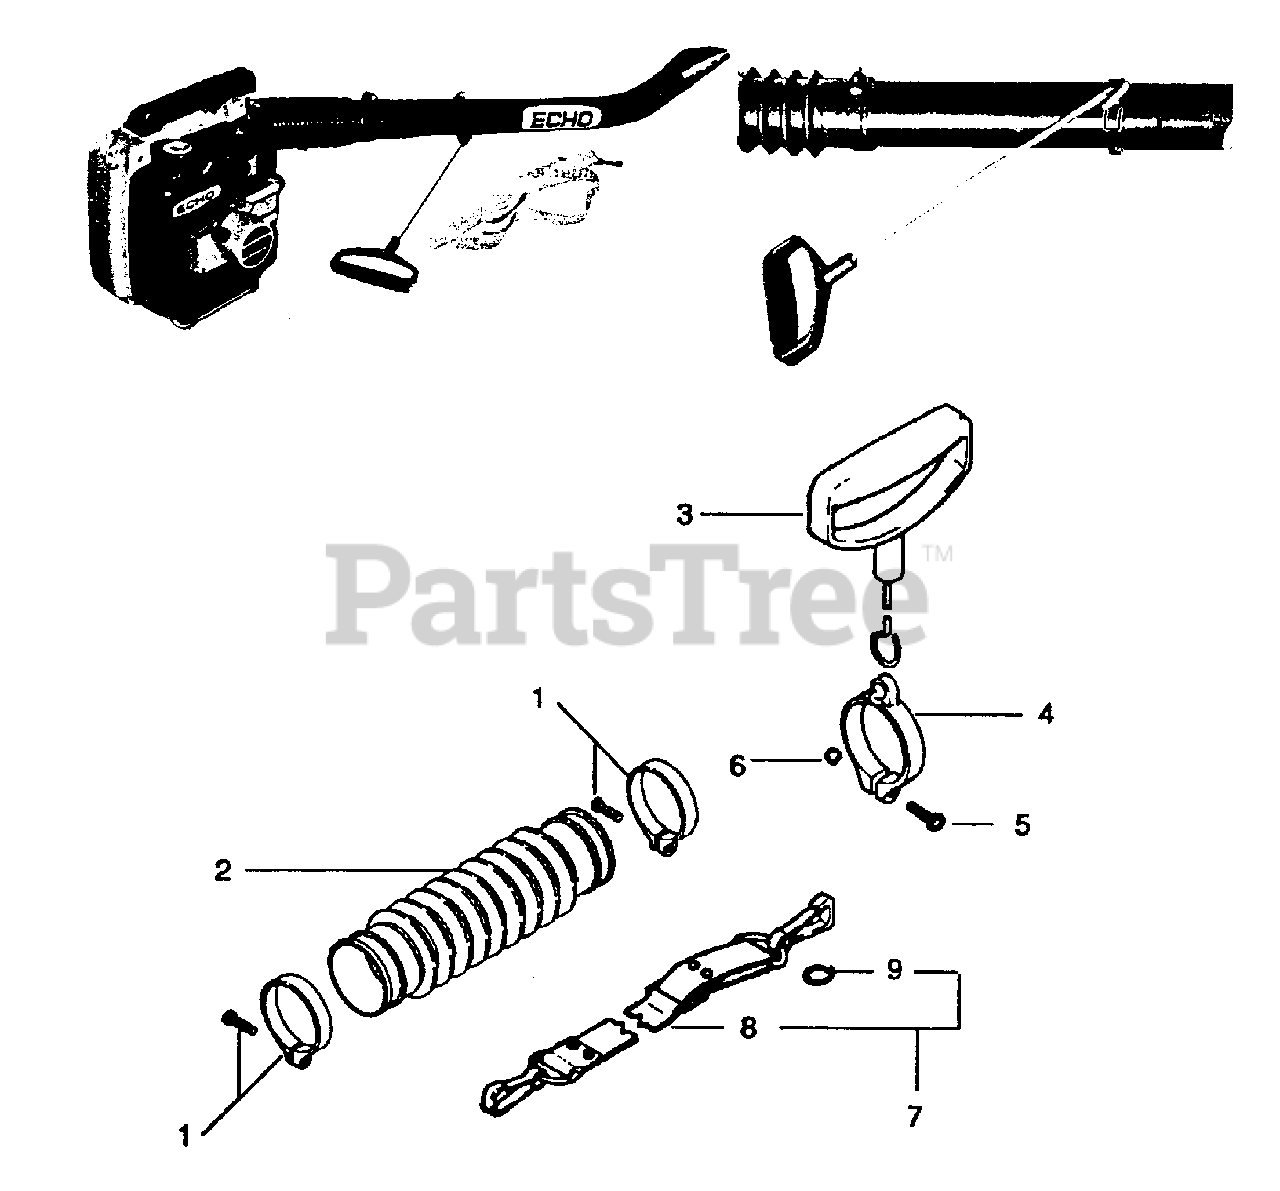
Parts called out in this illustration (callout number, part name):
1	CLAMP KIT
2	TUBE, BLOWER - FLEXIBLE
3	HANDLE - LEFT
4	CLAMP, HANDLE
5	SCREW - 5X25
7	SHOULDER STRAP ASSY
8	SHOULDER STRAP ASSY
9	RING
